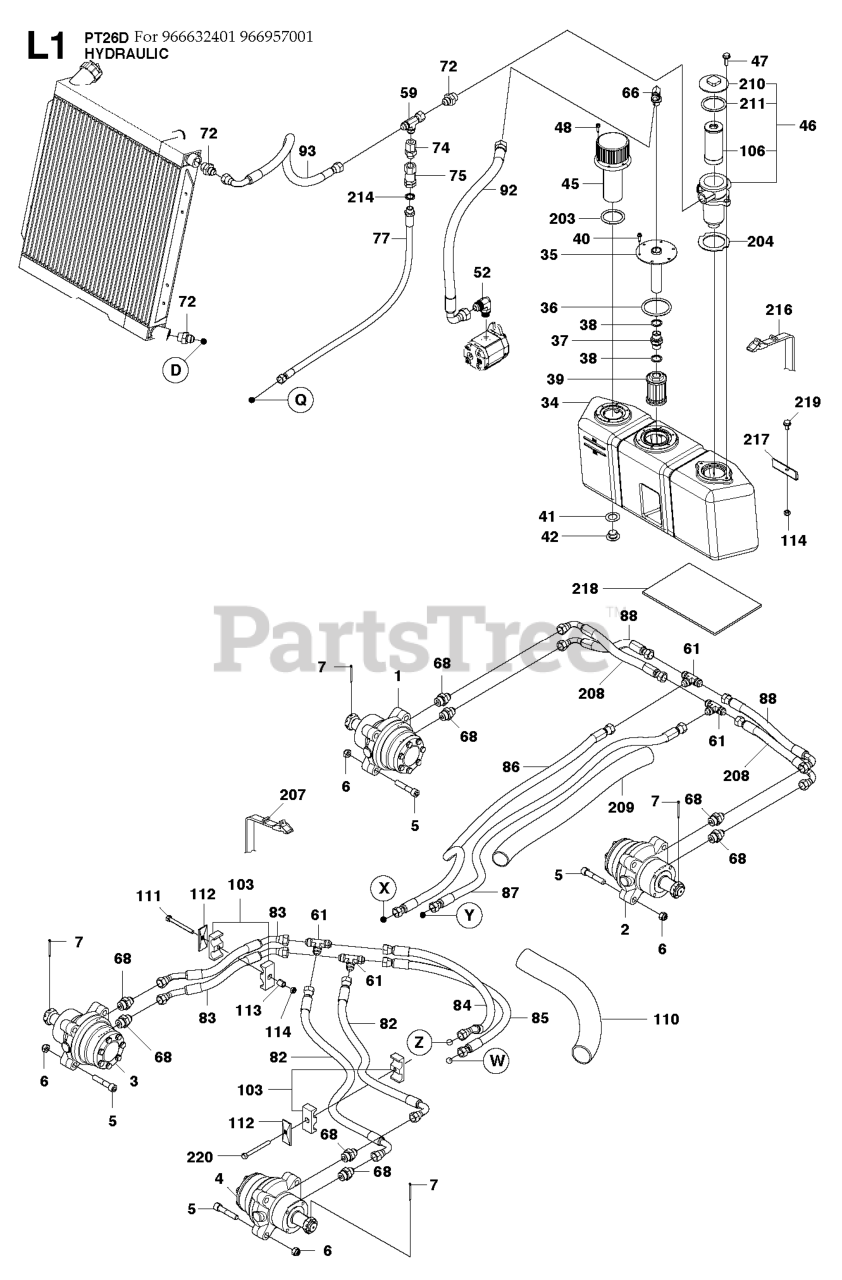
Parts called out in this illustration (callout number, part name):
1	WHEEL MOTOR 125 CW
2	WHEEL MOTOR 125 CCW
3	WHEEL MOTOR 160 CW
4	WHEEL MOTOR 160 CCW
7	COTTER PIN
36	O-RING 61.2X5.7 NITRIL
37	PIPE FITTING G STRAIGHT 1/2-1/
39	FILTER PUMP SUCTION, AWD
46	FILTER HOLDER
61	PIPE FITTING JIC T 3/4"
74	PIPE FITTING JIC-BSPP STRAIGHT
75	CHECK VALVE 2BAR
114	LOCKNUT M8
203	O-RING 47.2X5.7 NITRIL
209	HOSE GUARD D=43 L=500
210	FILTER HOLDER
211	O-RING 47.2X5.7 NITRIL
